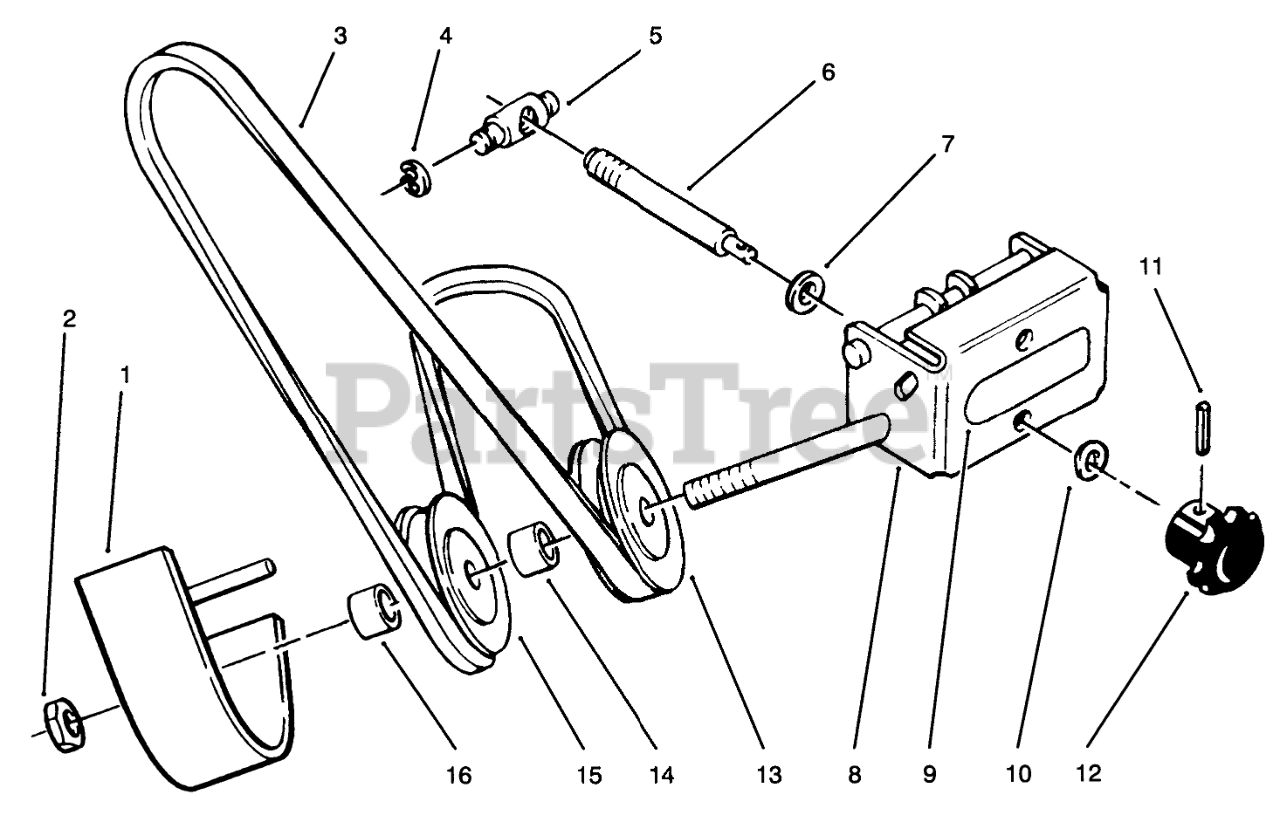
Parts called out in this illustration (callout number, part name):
1	Belt Cover
2	Nut
3	V-BELT
4	RING-RETAINING
5	TRUNNION-DOUBLE
6	ROD ADJ
7	WASHER-FLAT
8	Front Support
9	Decal-Attac-O-Matic
10	WASHER-SPRING
11	PIN-ROLL
12	KNOB-ADJUSTMENT
13	Pulley-V
14	SPACER
15	PULLEY-FLAT IDLER
16	SPACER-OUTER
